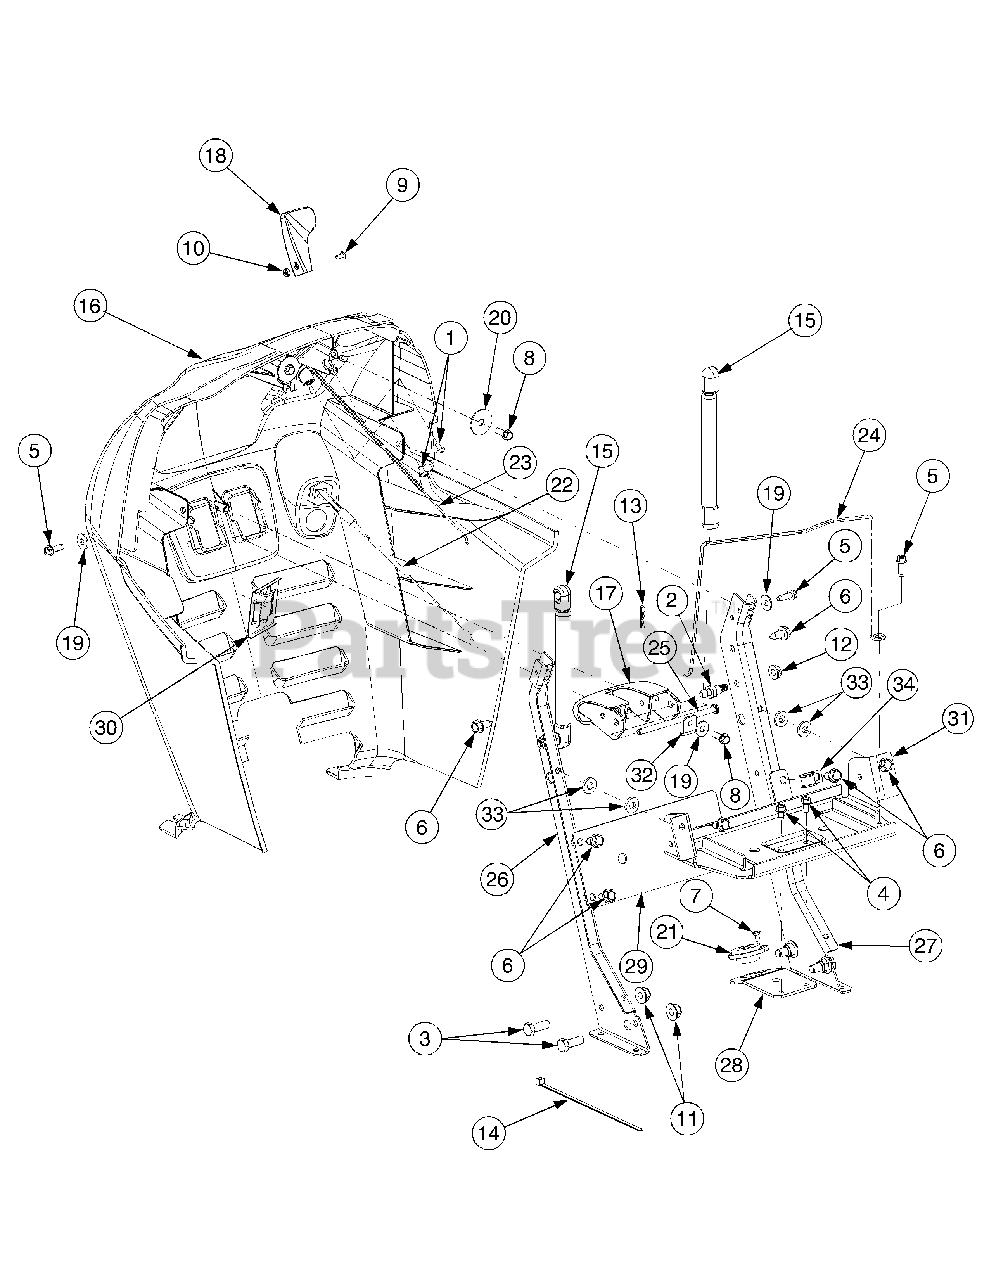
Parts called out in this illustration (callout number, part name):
1	Screw, #10-24 X .375
2	Screw, Ball Shoulder. 5/16-18 x .48
3	Screw, Hex Cap, 5/16-18 x 1.0 GR5
4	Screw, Self-tapping, 1/4-20, 0.500
5	Screw, Hx. Wash. Hd, Tapp. 1/4-20 x .75
6	Screw, Hx. Wash. Hd, Tapp, 5/16-12 x .75
7	Screw, Oval Cntrsnk, #10-16 x .625
8	Screw, 1/4-15, 0.750
9	Screw, Truss Mach., #8-32 x .375
10	Nut, Hex, #8-32 GrA
11	Nut, Hx Insert Flange Lck, 5/16-18 GrF
12	Nut, Hex Flange Lock, 5/16-18 GR5
13	Internal Cotter Pin, .072 x 1.13
14	Tie, Cable
15	Cylinder, Gas
16	Dash
17	Lever, Dash, Cruise
18	Knob, Throttle Control
19	Washer, Flat, .28 x .74 x .063
20	Washer, Flat, .33 x 1.25 x .06 HT
21	Bearing, Steering Column
22	Cable, Choke
23	Cable, Throttle Control
25	Rod, .25 x 4.55
33	Washer, Flat, .344 x .75 x .12
34	Clamp, 9/16
